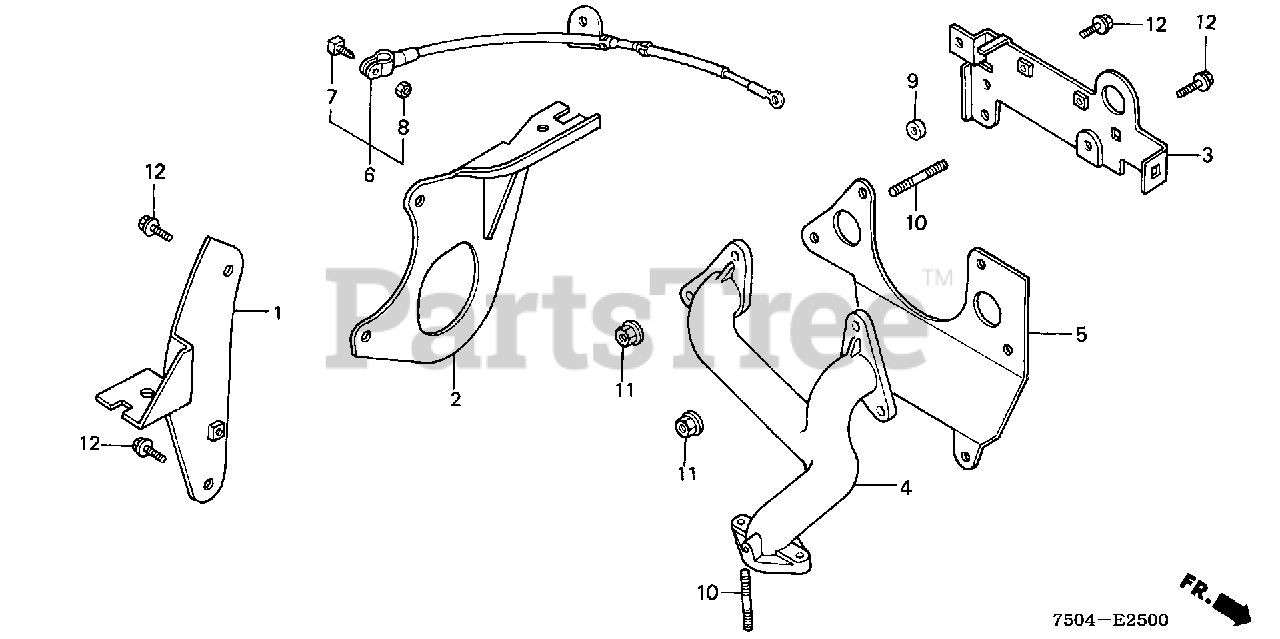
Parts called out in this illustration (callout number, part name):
1	STAY, R. ENGINE MOUNTING
2	STAY, L. ENGINE MOUNTING
3	HOOK, ENGINE
4	MANIFOLD, EX.
5	GASKET, EX.
6	CABLE ASSY., GROUND
7	BOLT, BATTERY TERMINAL (SUMITOMO)
7	BOLT, BATTERY TERMINAL
8	NUT, BATTERY TERMINAL (SUMITOMO)
9	WASHER, PLAIN
10	BOLT, STUD (8X35)
11	NUT, FLANGE (8MM)
12	BOLT, FLANGE (8X20)
